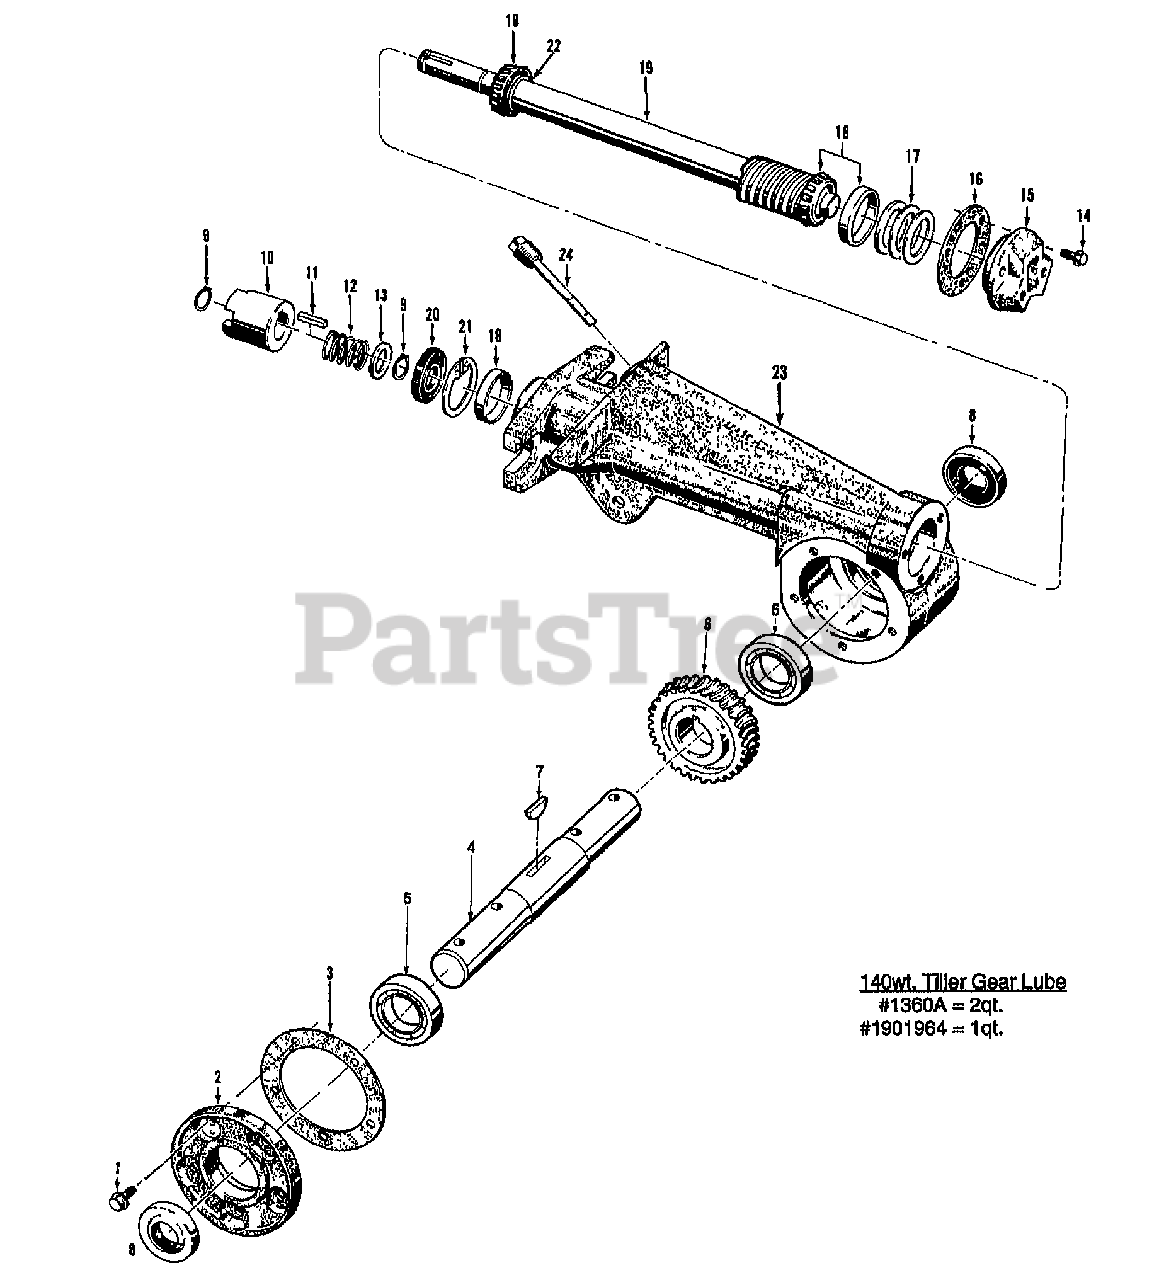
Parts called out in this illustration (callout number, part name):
1	KIT-SEALING SCRS (5)W/LIT
2	COVER-TILLER HSG MACH
3	GASKET-TILLER COVER
4	SHAFT-TILLER MACH HORSE
5	BEARING-BALL
6	GEAR-WORM MACH RTH HORSE
7	KEY-WOODRUFF .25X1.12
8	SEAL-TILLER SHAFT
9	RING-RETAIN EXT .707 ID
10	KIT-CLUTCH DOGS TILLER
10	CLUTCH-DOG HORSE TRANS
11	KEY-.188 SQX1.0
12	SPRING (TC)
13	SHIM-1.0X.7656X.062
14	KIT-SEALING SCRS (3)
15	CAP-REAR #1115
16	GASKET-BRG COVER
17	SHIM-1.75X1.5X.01
17	SHIM-1.75X1.5X.03
17	SHIM-1.75X1.5X.005
17	SHIM-1.75X1.5X.062
18	KIT-BRG CONE&RACE-DRIVESHAFT
19	KIT-TILLER DR SHAFT
20	SEAL-OIL DRIVESHAFT
21	RING-RETAINING 5000-181
22	SHIM-1.0X.7656X.062
23	HOUSING-TILLER W/SLEEVE
24	ASSM-DIPSTICK HORSE TRANS
